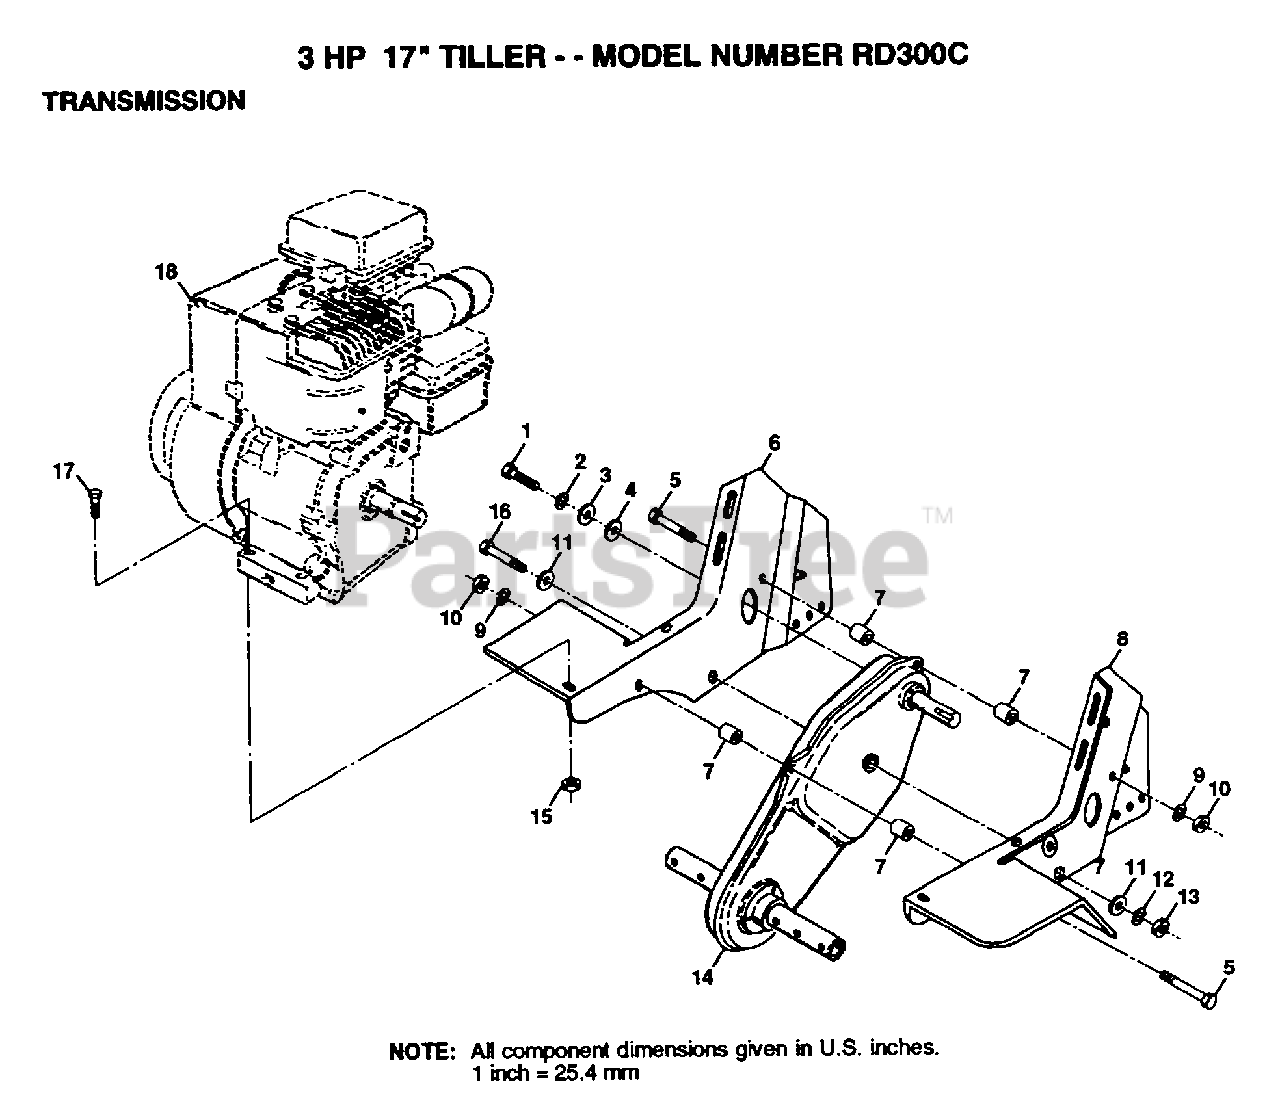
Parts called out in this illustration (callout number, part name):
1	BOLT
2	LOCKWASHER
3	WASHER
4	WASHER
6	"BRKT,ENG RH"
7	SPLIT SPACER RT
8	ENGINE BRKT LH
9	LOCKWASHER
10	NUT.HEX.5/16-18
11	WASHER
12	LOCKWASHER
13	GRIPCO NUT
16	BOLT.3/8-24X3.75
17	BOLT.HEX.5/16-1.5
18	ENGINE, SEE BREAKDOWN
